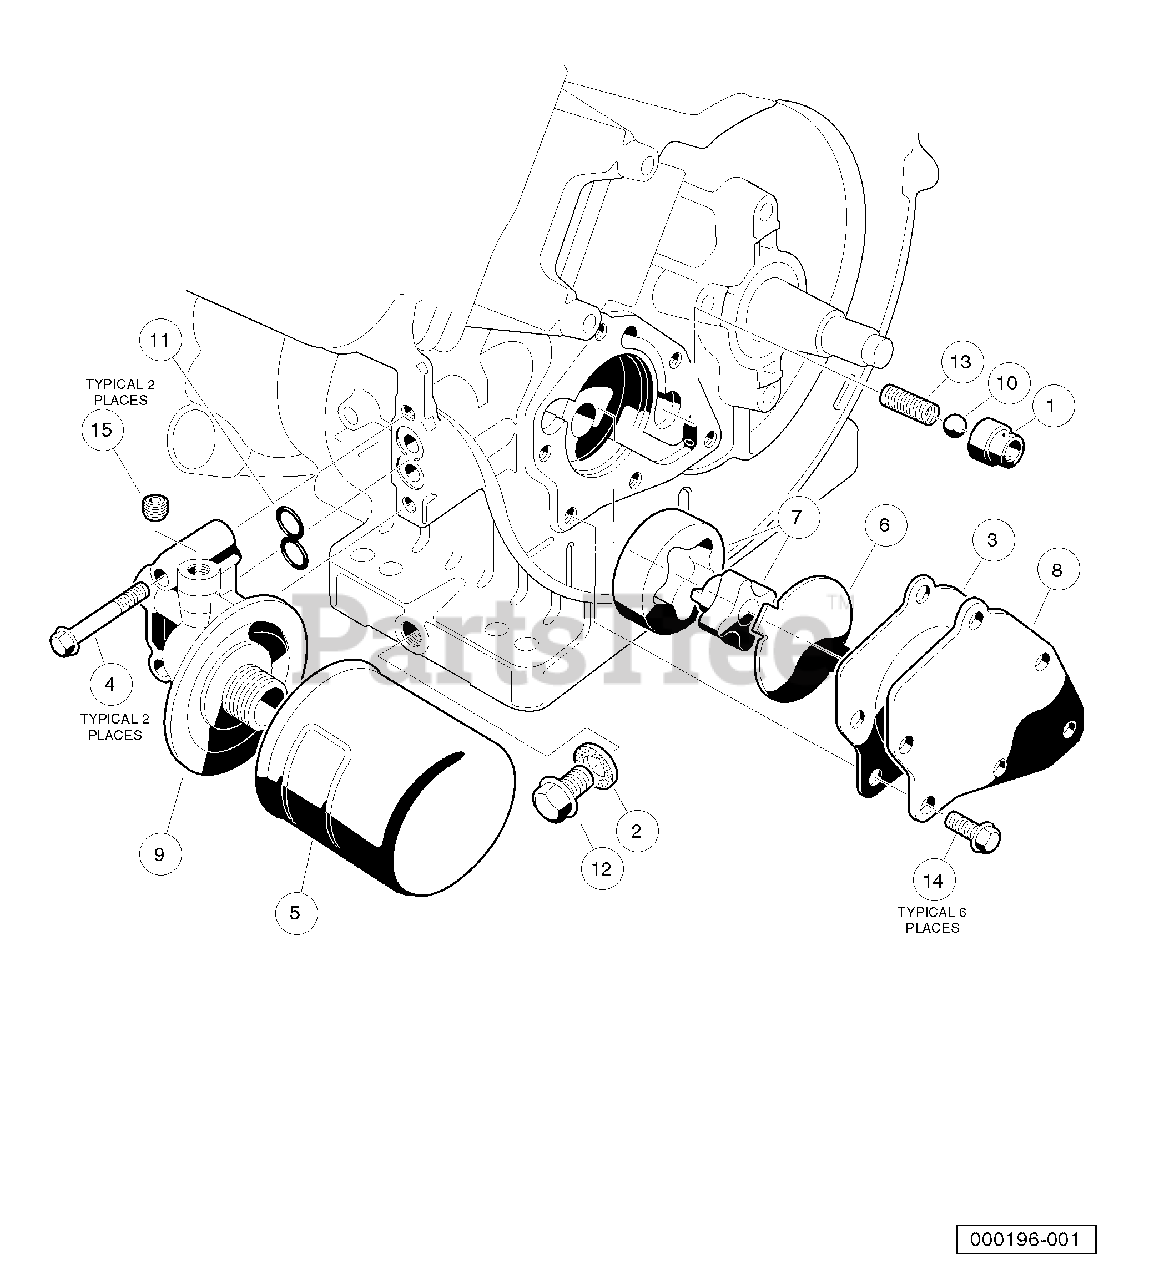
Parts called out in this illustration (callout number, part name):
1	Seat, Value Oil Press Relief
2	Gasket, Drain Plug
3	Gasket, Oil Pump
4	Bolt, Flange Head
5	Filter, Oil
6	Plate, Oil Pump
7	Oil Pump And Rotor
8	Cover, Pump
9	Bracket, Oil Filter Mount
10	Ball, Steel, Press, Relief
12	Plug, Drain
14	Bolt, Flanged
